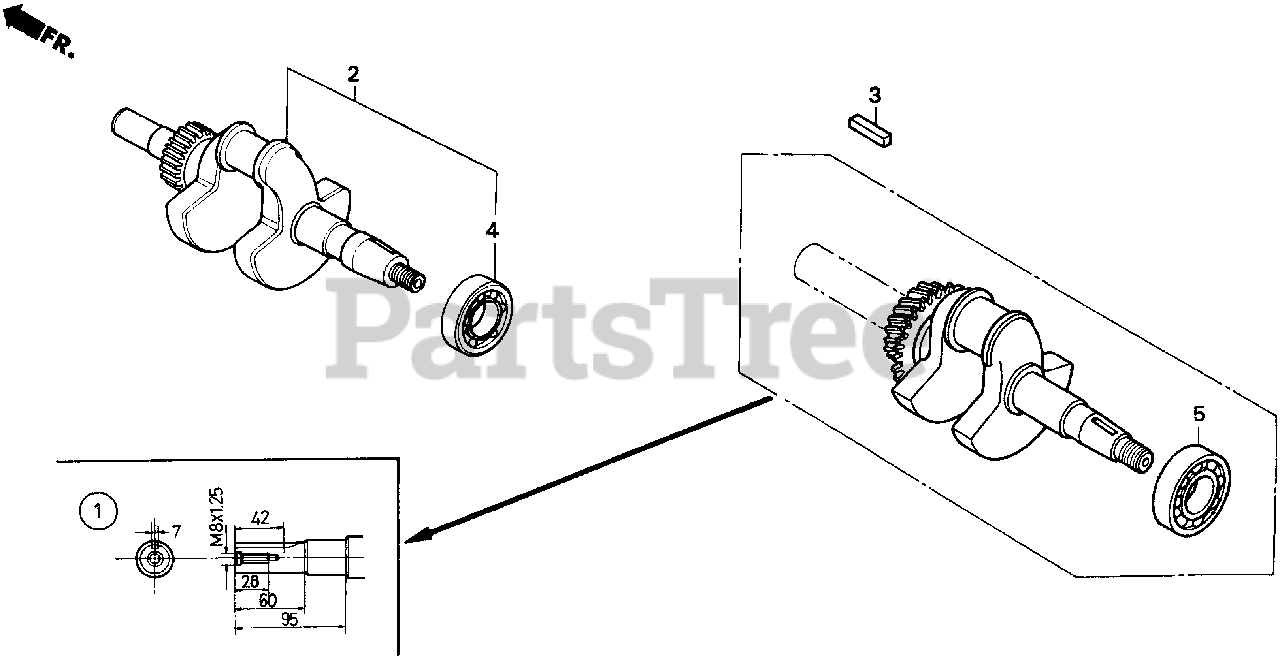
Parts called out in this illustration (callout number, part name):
1	CRANKSHAFT (S-TYPE)
3	KEY, SPECIAL WOODRUFF (25X18)
5	BEARING, RADIAL BALL (6206)
